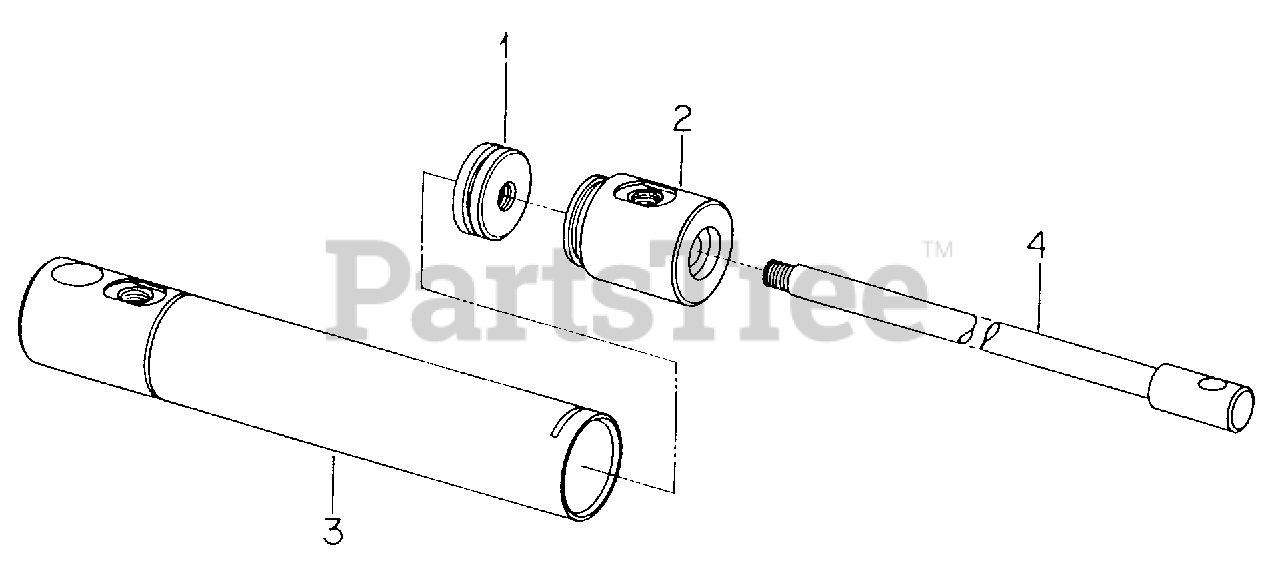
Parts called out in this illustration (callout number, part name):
1	Piston, Hydraulic Cylinder
2	End, Hydraulic Cylinder Front
3	Body, Hydraulic Cylinder
4	Rod, Hydraulic Cylinder Piston
